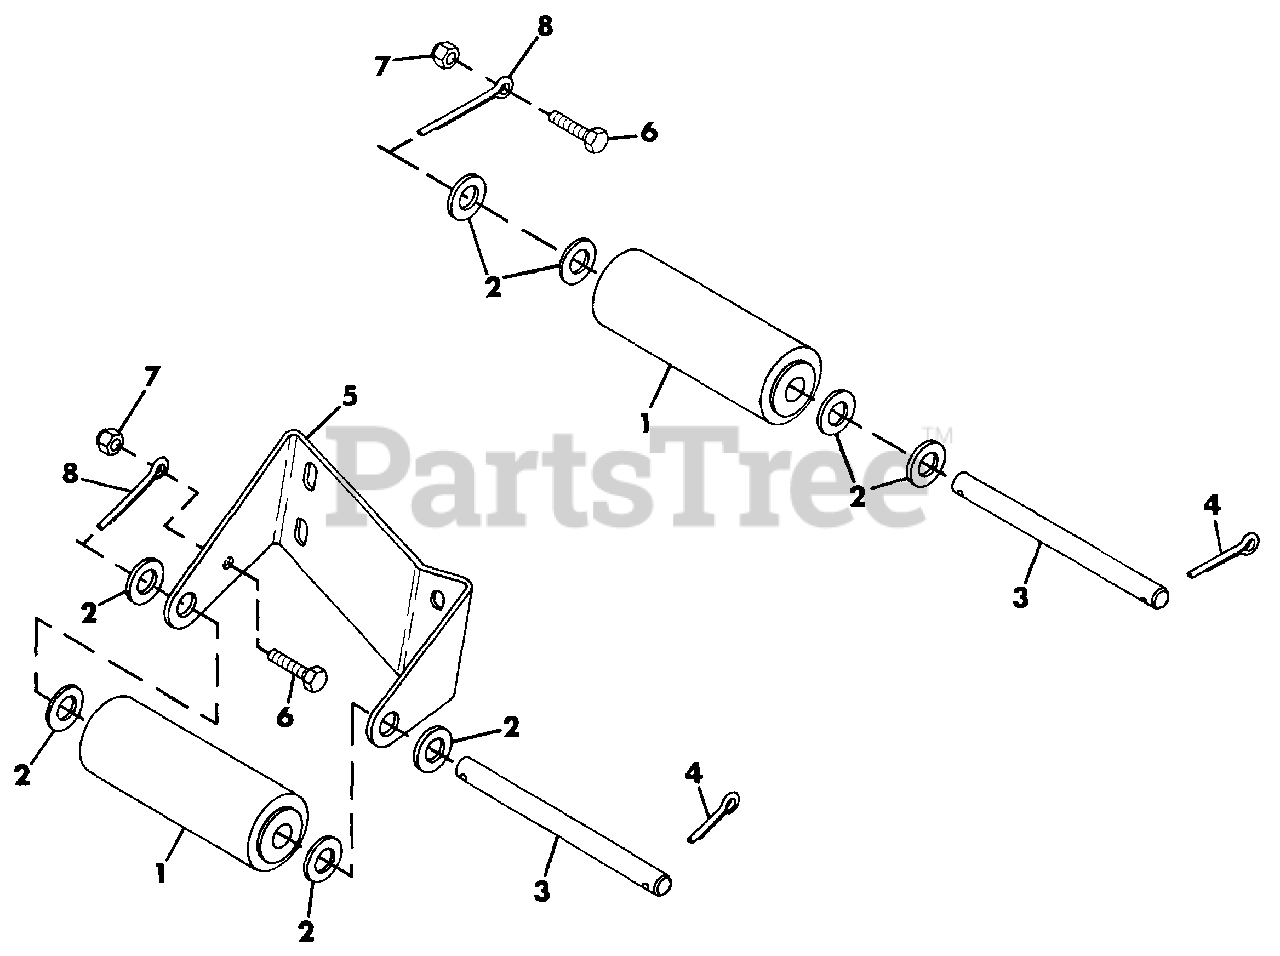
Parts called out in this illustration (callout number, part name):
1	ROLLER, GAUGE
2	WASHER, FLAT .656X1.312X.095
3	SHAFT, CENTER ROLLER
4	PIN, COTTER .25X1.00
5	BRACKET, ROLLER FRONT
6	BOLT, HEX 1/4-20X.75
7	NUT, HEX 1/4-20
8	PIN, COTTER .25X2.00
